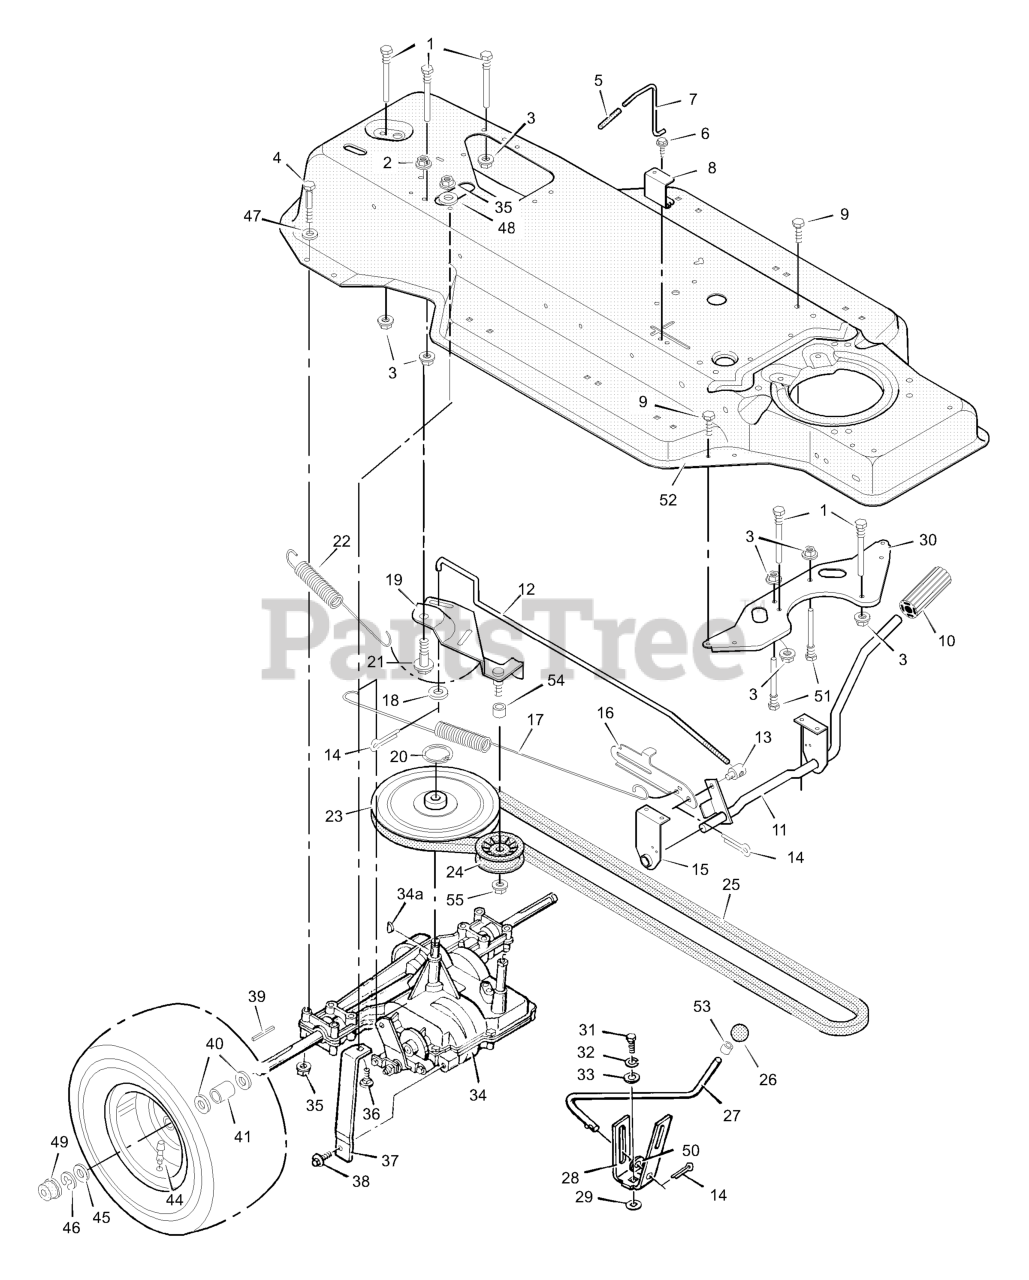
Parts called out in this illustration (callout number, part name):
1	Guide, Belt
2	Locknut, Flange
3	Nut, Flange
4	Bolt, Hex
7	Rod, Control -Park Brake
8	Guide, Bracket
10	Clutch and Brake Pedal
11	Lever Assembly
12	Rod, Clutch
13	Nut, Adjustable
14	Pin, Cotter
15	Bracket, Support
16	Latch, Park Brake
17	Spring, Brake Extension
18	Washer
19	Bracket Assembly, Idler
20	Ring, Retainer
21	Bolt, Shoulder
22	Spring, Drive Extension
23	Pulley, Motion Drive
24	Pulley, Backside Idler
25	Belt, Motion Drive
26	Knob, Shift Lever
27	Lever, Shift
28	Yoke, Shift
30	Plate, Belt Guide
31	Bolt, Hex
32	Lockwasher
34	Transaxle, Peerless **
34A	Woodruff Key No. 9
35	Nut, Flange
36	Bolt, Carriage
37	Support, Transaxle
39	Key, Square
41	Spacer, Transaxle
43	Wheel & Tire Assembly
44	Stem, Valve
47	Washer
49	Hub Cap
50	Washer
51	Guide, Belt
52	Frame Assembly
53	Ring, Tolerance
55	Nut
